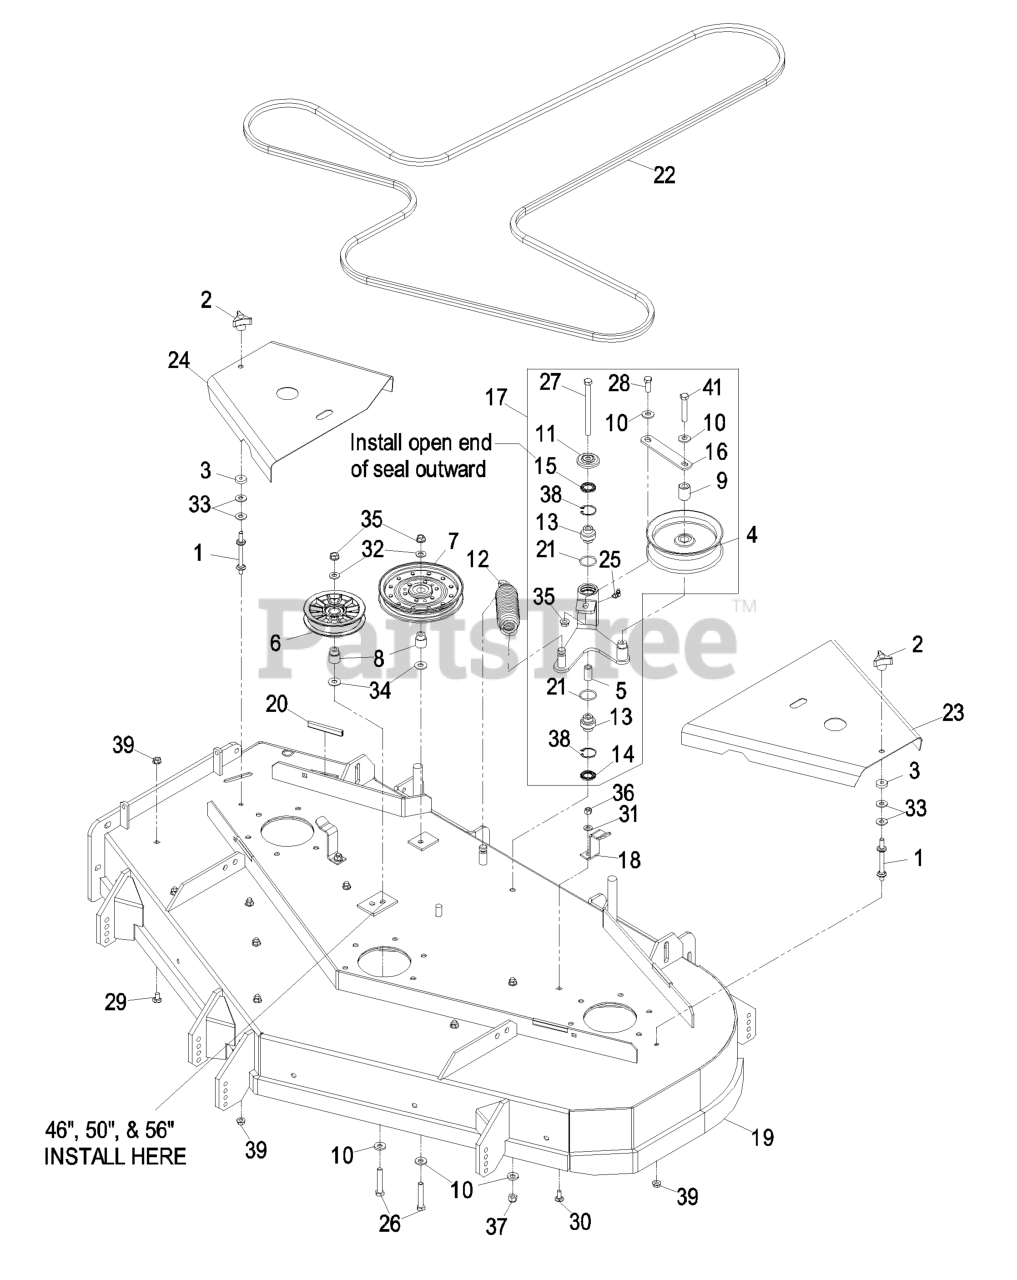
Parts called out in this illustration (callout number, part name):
1	STUD-SHIELD, BELT (SHORT)
2	KNOB-3 PRONG
5	BUSHING-LEVER, LIFT
6	PULLEY,IDLER 5"
7	PULLEY-IDLER
8	BUSHING-IDLER
10	WASHER-BELLEVILLE
11	GUARD-TOP
13	BEARING-SPHERICAL
14	SEAL-LIP, DOUBLE
15	SEAL-LIP, SINGLE
16	PLATE,GUIDE BELT (PLTD)
17	KIT,IDLER ARM W/BEARINGS
18	LATCH,BELT SHIELD
19	ASM, DECK 465 W/DECALS
20	STRIP-SEAL
22	BELT, B147.25
23	SHIELD, BELT LH 465 W/DEC
24	SHIELD, BELT RH 465 W/DEC
25	FITTING-GREASE, 90 DEG
26	SCREW-HH
27	SCREW-HH
28	SCREW-HH
29	SCREW-CARR
30	SCREW-CARR
31	WASHER-PLAIN
32	WASHER-FLAT
33	WASHER-FLAT
34	WASHER-FLAT
35	NUT-HHF, WHIZ
36	NUT-LOCK, NI
37	NUT-LOCK, NI
38	RING-SNAP
40	Asm, Deck Complete 46"
41	SCREW-HH
